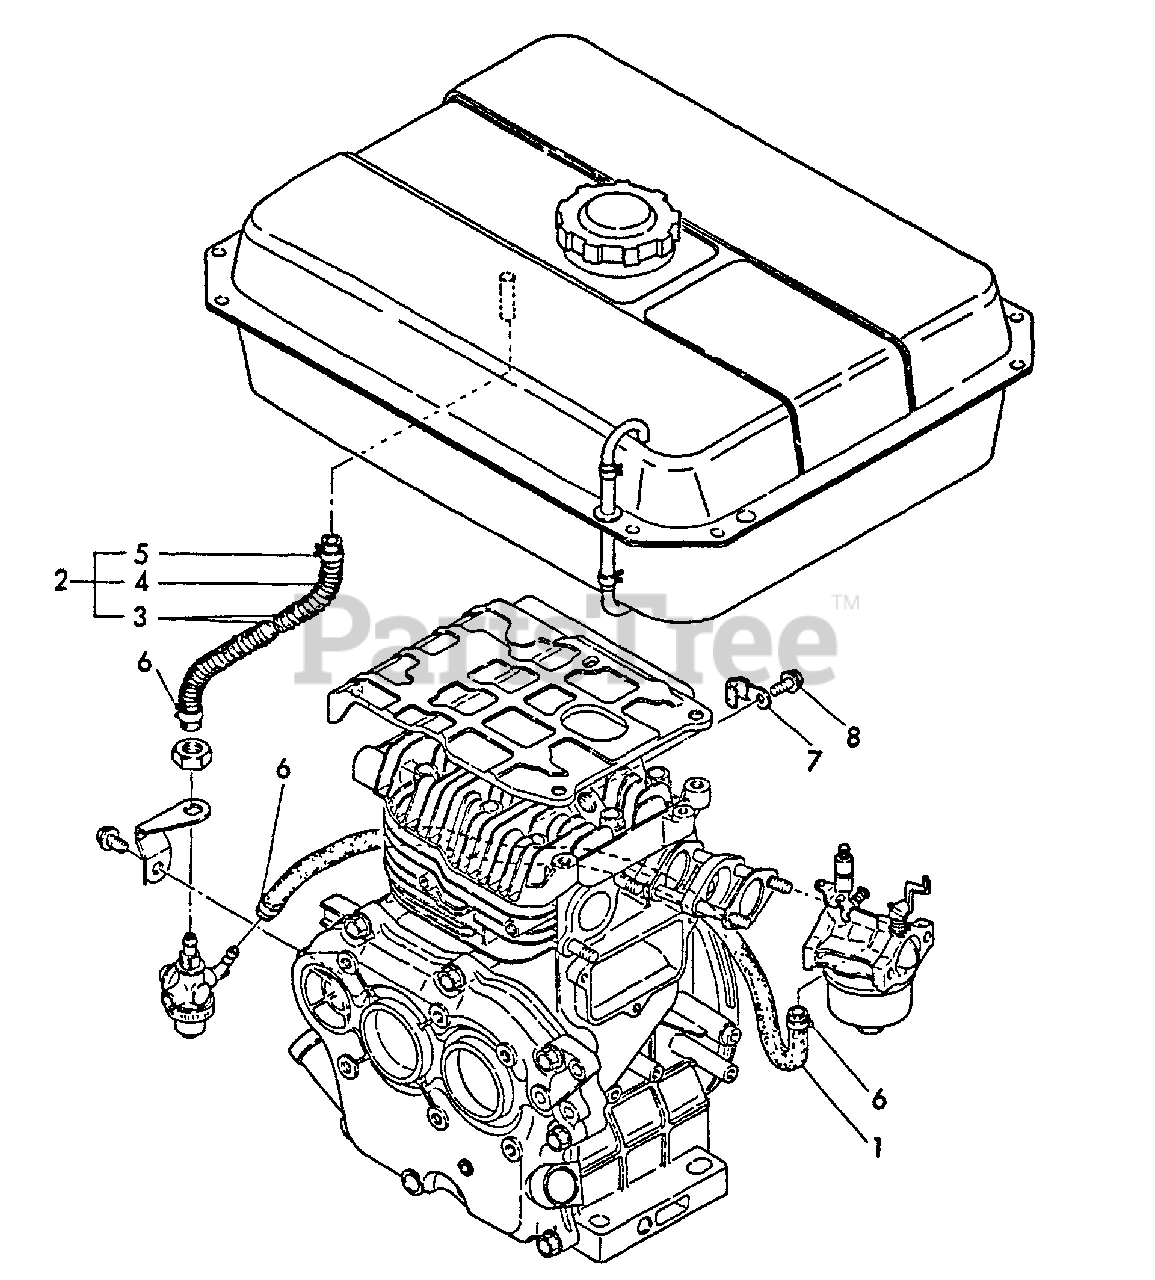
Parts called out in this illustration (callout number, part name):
1	PIPE - FUEL
2	PIPE - FUEL
3	PIPE - FUEL
4	SPRING, PROTECTIVE
5	CLAMP, HOSE - 10
6	CLAMP, HOSE - 10
7	CLAMP
8	BOLT - 6X8 -- PLATED
